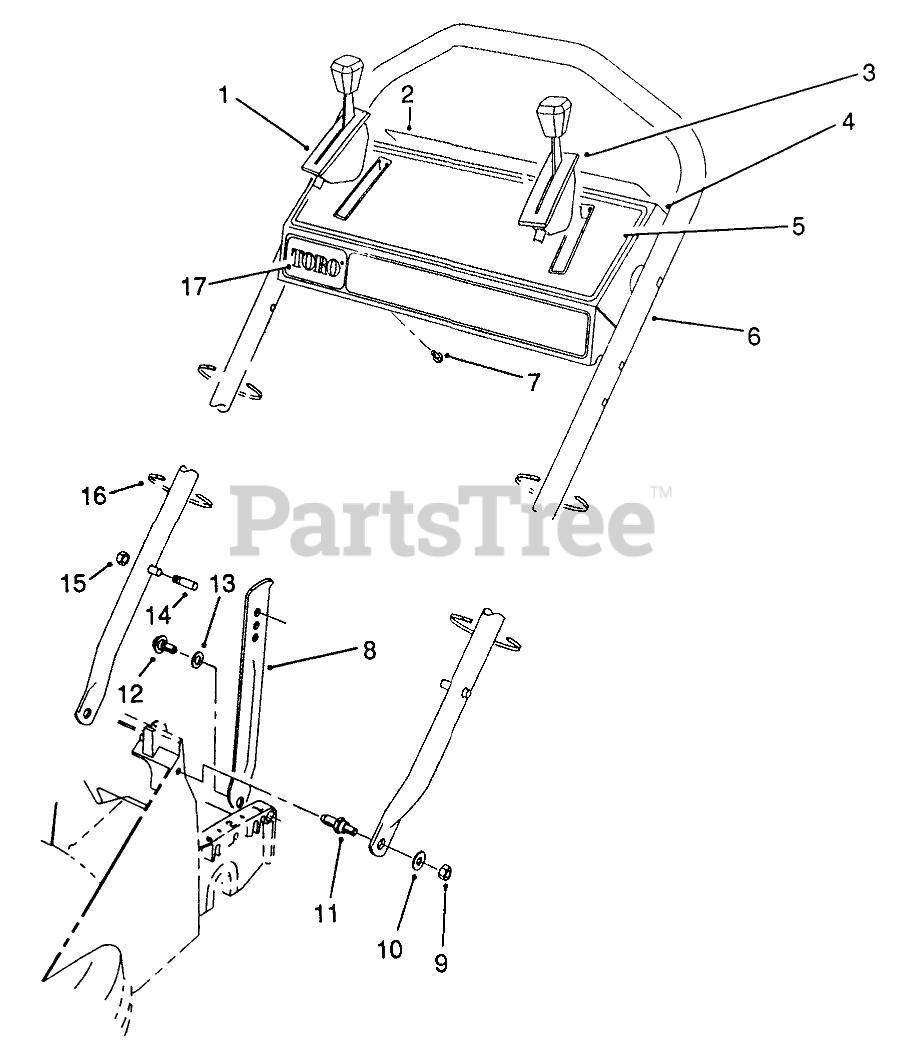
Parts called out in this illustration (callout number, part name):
1	Control-Ground Speed
2	DECAL-PANEL, DANGER
3	THROTTLE CONTROL
4	Control Panel Assembly (Incl. Ref. #2, 5 & 17)
5	DECAL - INSTRUCTION
6	HANDLE
7	SCREW-HWHTF
8	HANDLE LATCH
9	NUT-LOCK, NI
10	WASHER-PLAIN
11	SCREW - SHOULDER STUD
12	SCREW-SHOULDER
13	NYLON WASHER
14	HANDLE PIN
15	NUT-LOCK, NI
16	TIE-CABLE
17	DECAL - TORO PANEL
